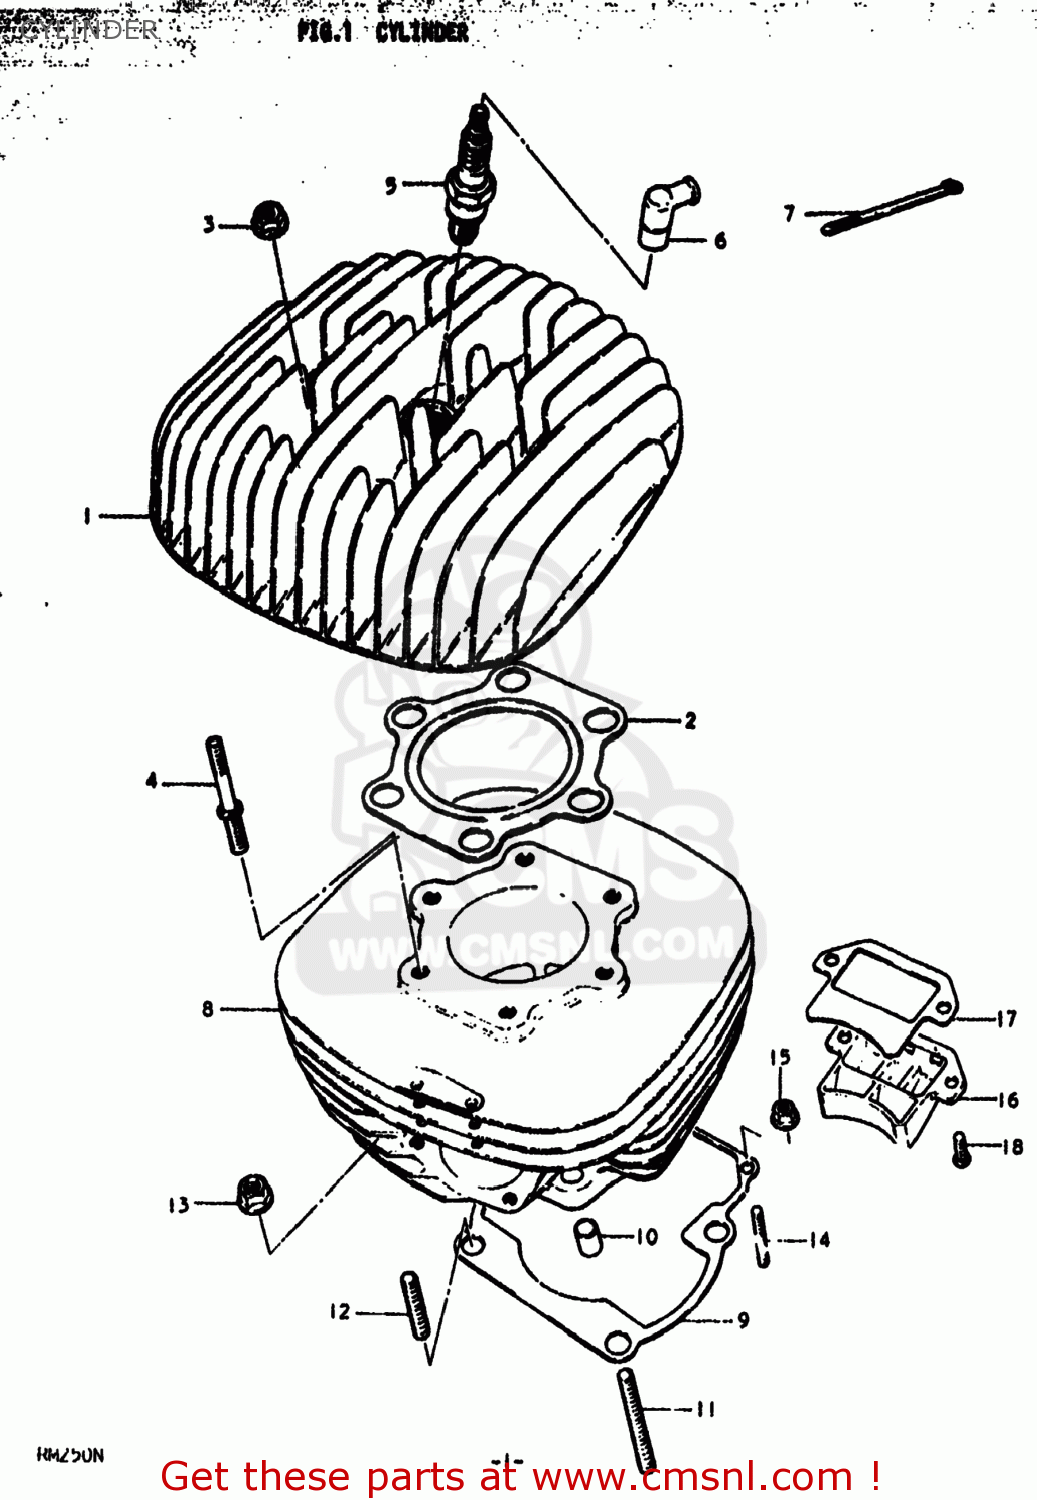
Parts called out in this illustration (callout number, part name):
1	HEAD,CYLINDER
2	GASKET,CYLINDER HEAD (NAS)
3	NUT
4	BOLT,STUD
5	SPARK PLUG N-2G CHMP
6	CAP,SPARK PLUG
7	CLAMP
8	CYLINDER
9	GASKET,CYLINDER (MCA)
10	PIN
11	STUD BOLT (L:40)
12	STUD 10X25
13	NUT
14	STUD 6X20
15	NUT
16	VALVE ASSEMBLY,REED
17	GASKET,REED VALVE (MCA)
18	SCREW
